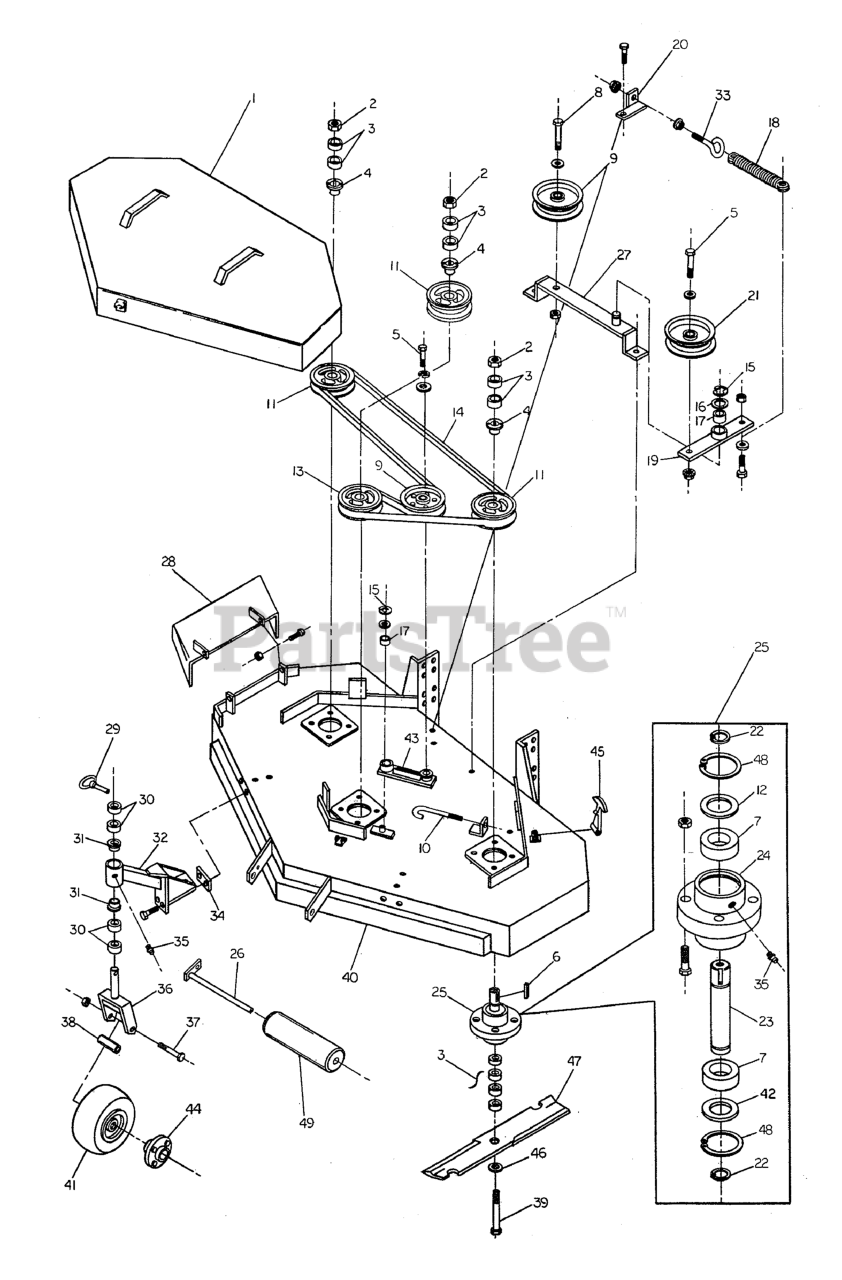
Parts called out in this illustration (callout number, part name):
1	Guard 52" Deck
2	NUT, 5/8-11 Hex
3	SPACER, .63 x 1.06 x .23
4	BUSHING, Tapered Hub
5	BOLT, 1/2-20 X 2-1/4 GD5 CZ
6	KEY, 1/4 SQ. X 2-1/2
7	BEARING
8	BOLT, 3/8-16 X 3" GD5 CZ
9	PULLEY, Backside Idler
11	PULLEY, Spindle
12	SPINDLE WASHER, Top
13	SPINDLE PULLEY
14	BELT, Blade Spindle
15	C-CLIP
16	SHIM
17	BUSHING, Brass
18	SPRING, Extension
19	IDLER ARM, Complete
20	Spring Anchor
21	PULLEY, V-Idler
22	SNAP RING, External
23	SPINDLE SHAFT
24	SPINDLE HOUSING
25	SPINDLE ASSEMBLY, Complete
27	Idler Mount
28	CHUTE, DISCHARGE WELDMENT
29	PIN, Lynch
30	SPACER, 1.02 x 1.56 x .50
31	BUSHING, Flange
32	Caster Support
33	EYEBOLT
34	Caster Mount Spacer
35	GREASE FITTING
36	YOKE, Caster
37	BOLT, 1/2-13 x 5-1/2
38	AXLE, Caster Wheel
39	BOLT, 5/8-11 x 9-1/2
40	52" MOWER HOUSING
41	WHEEL & TIRE ASSEMBLY, White, 9 x 3.5 x 4, Complete
41	TIRE, Front, 9 x 3.5 x 4
41	HUB & BEARING ASSEMBLY, Complete, White
42	SPINDLE WASHER, Bottom
43	IDLER ARM
44	4 BOLT HUB W/ BEARING
44	Hub Complete (Stamped T)
45	RUBBER LATCH
46	WASHER, 5/8" USS
47	MOWER BLADE, 18"
48	SNAP RING, Internal
49	ROLLER
